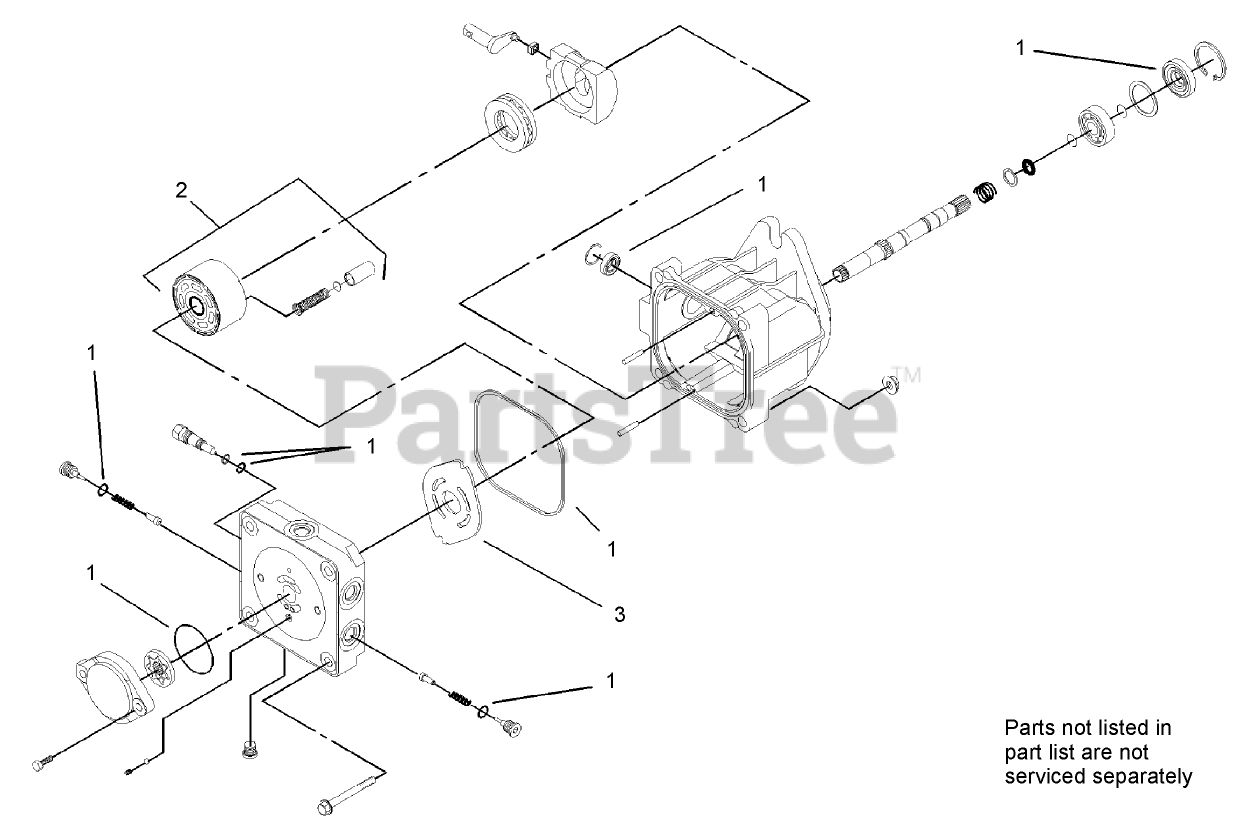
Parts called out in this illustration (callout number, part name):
1	OVERHAUL SEAL KIT
2	CYLINDER BLOCK ASM
3	PLATE-VALVE
